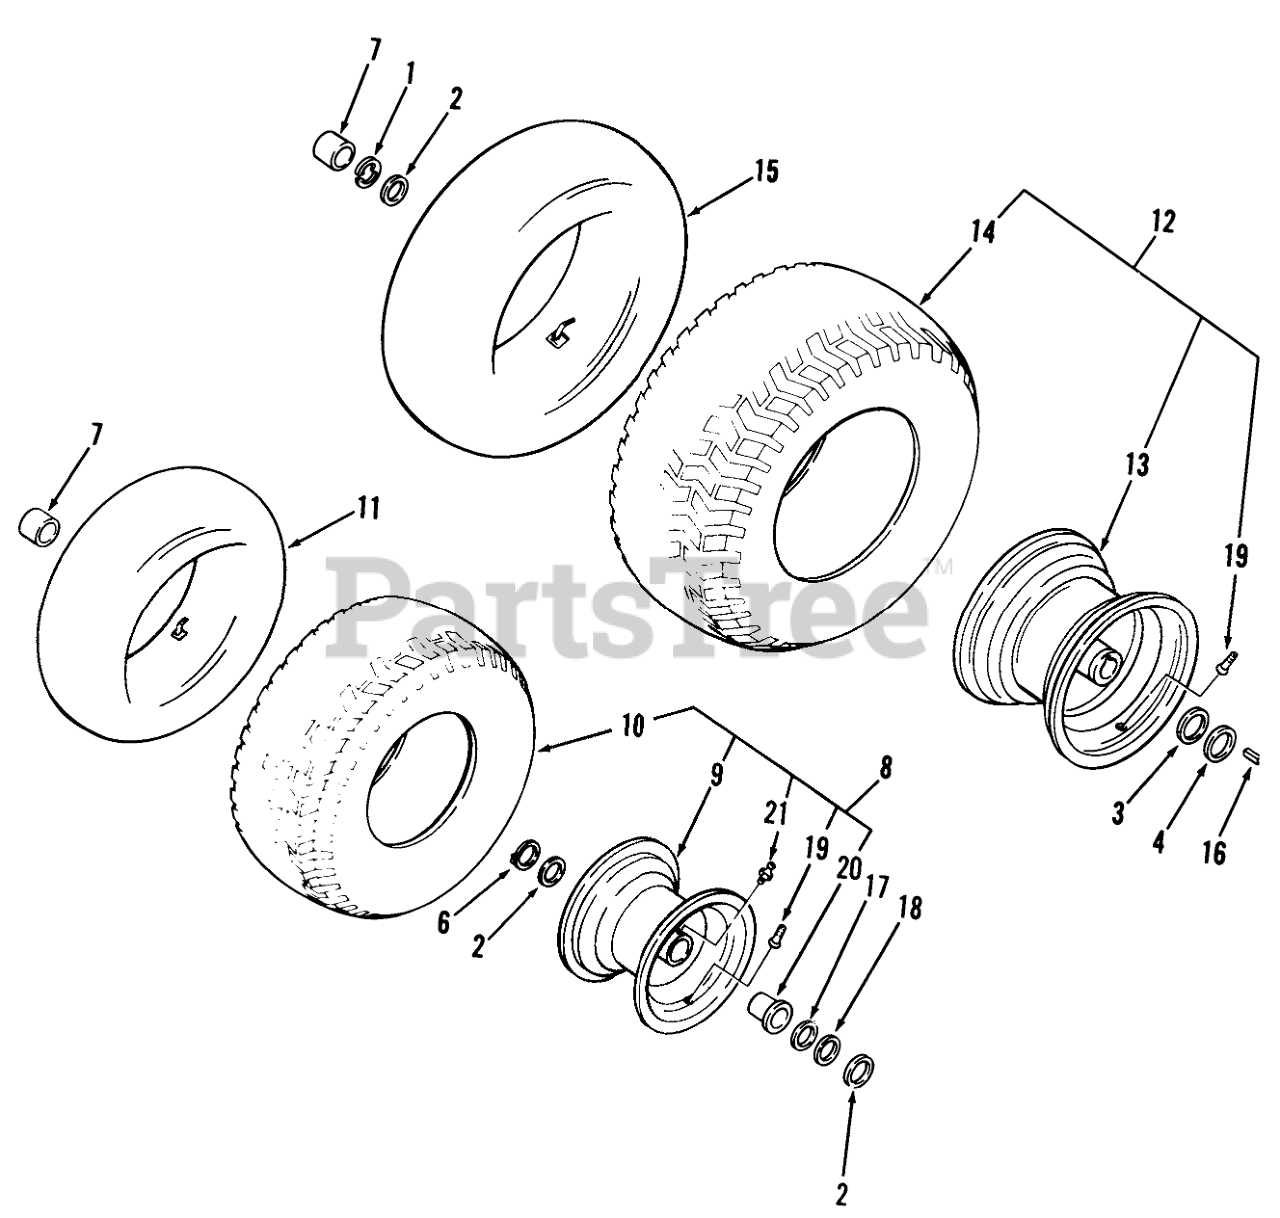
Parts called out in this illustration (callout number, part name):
1	E RING
1	E Ring
2	Washer
2	WASHER-FLAT
3	Washer
3	WASHER-SHIM
4	WASHER
6	Snap Ring
7	HUB CAP-FLAT BLACK
7	HUB CAP
8	Wheel & Tire Assembly
9	ASSY-RIM
11	Tube (Service Only)
12	Assy-Wheel & Tire Rear
13	ASSY RIM
13	RIM ASSY
14	Rear Tire 20 x 10.0-10.0
16	Key
16	SQ KEY
17	WASHER
18	WASHER-SHIM
19	VALVE
20	FLANGE BEARING
21	Zerk
